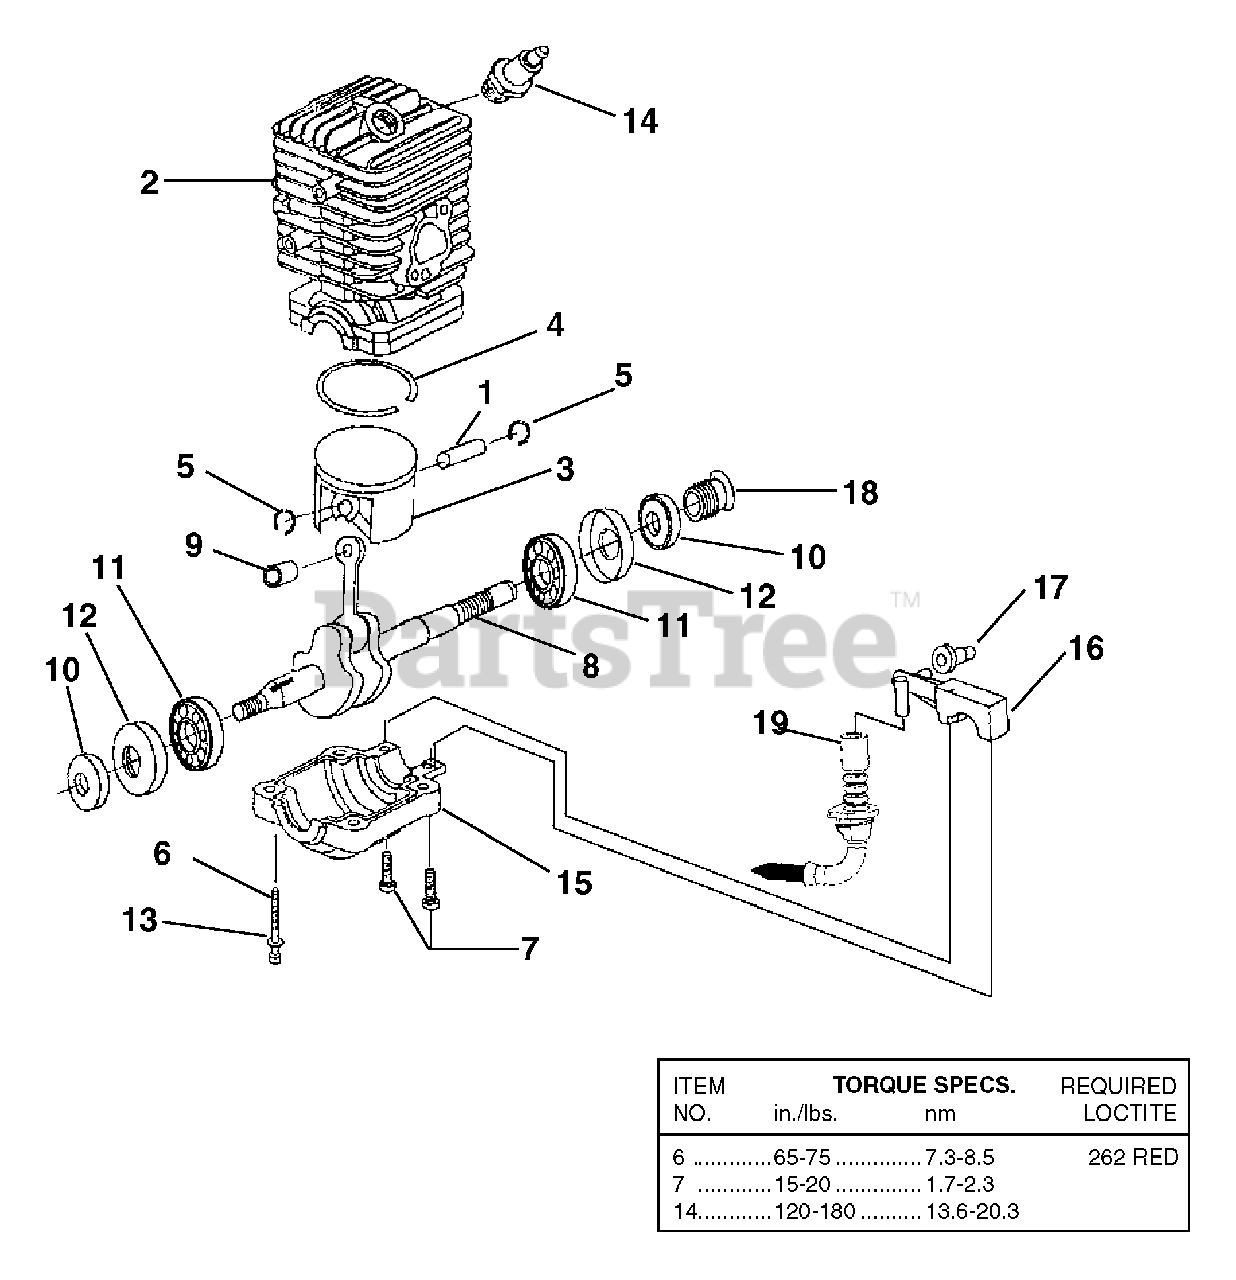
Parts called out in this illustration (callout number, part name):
1	PISTON PIN
2	CYLINDER MACH/PLATED
3	45CC PISTON (MACH)
4	PISTON RING
5	RETAINING RING
6	SCREW TORX PLUS CAP-SOCKET HD
7	SCREW, (8/32 X 5/8 in. PAN HD TORX)
8	45CC SINTERED METAL CRANKSHAFT ASSY.
9	NEEDLE BEARING
10	SHAFT SEAL
11	BALL BEARING
12	BEARING CASE
13	FLAT WASHER
14	SPARK PLUG
15	CRANKCASE (45CC) CS
16	OIL PUMP ASSEMBLY
17	GROMMET, OIL OUTLET
18	LEFT HAND WORM
19	OIL INTAKE TUBE W/FILTER
